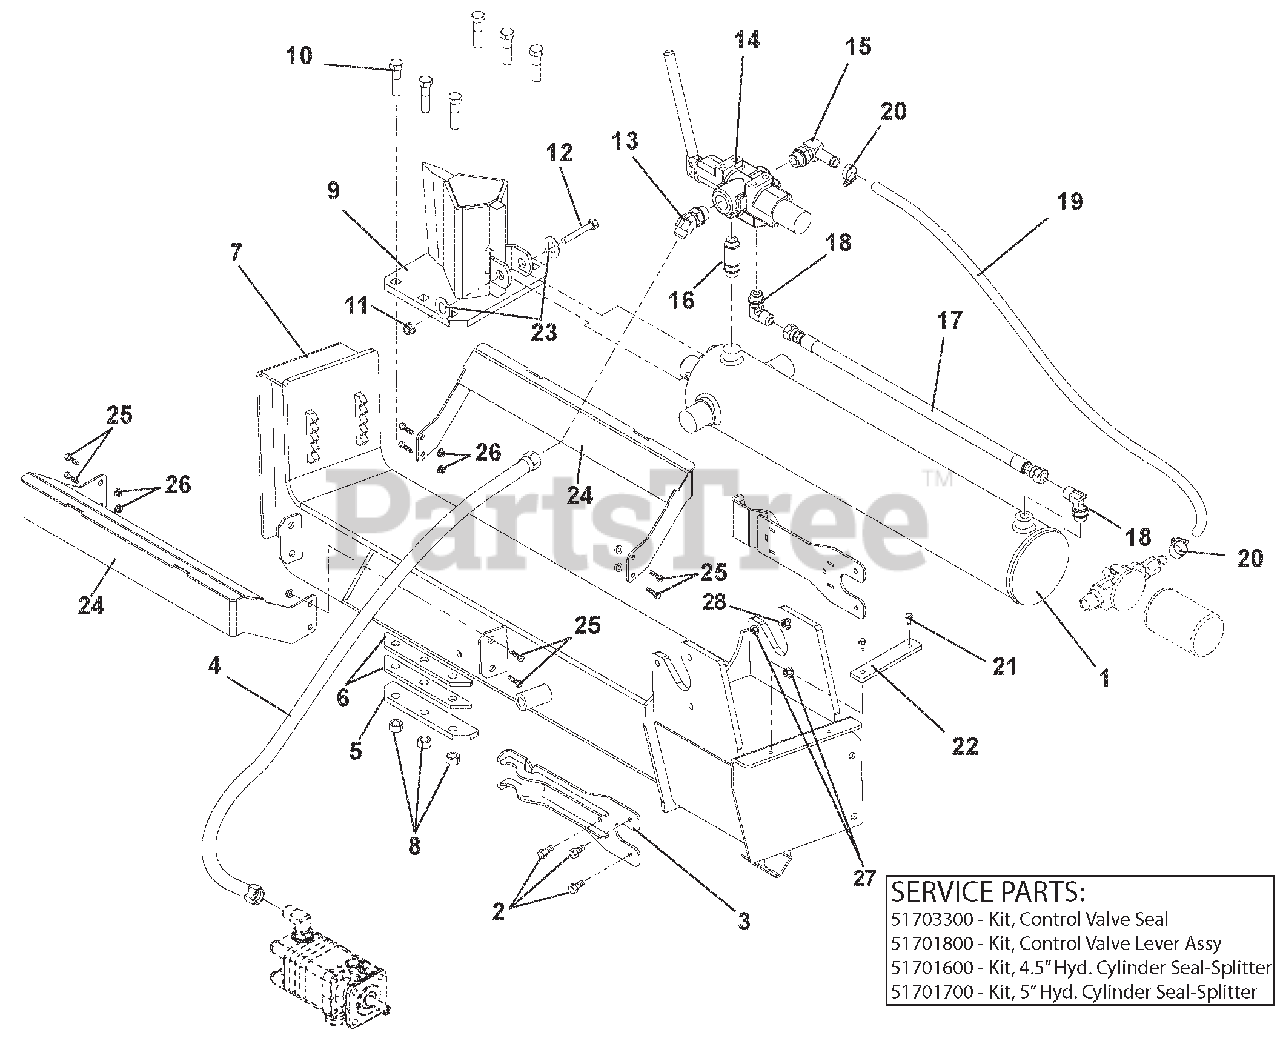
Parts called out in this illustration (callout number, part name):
1	CYLINDER,4.5 W/DECALS
1	KIT,4.5" HYD CYL SEAL-SPLITTER
1	CYLINDER, 5' W/DECALS
1	KIT, 5" HYD CYL SEAL-SPLITTER
2	@BLT-HEX .31-18X1.00 GR5 YWZC
3	WLDMT, PLATE - STRIPPER
4	HOSE, ASM - 46"
5	RETAINER,WEDGE
6	SPACER, WEDGE
7	WLDMT, BEAM - 27/34T SPLITTER
8	NUT-LK-CTR-FLG .50-13 YWZC
9	WMT, WEDGE - SPLITTER
10	BLT-RDHDSQNKFTH.50-13X2 G8YWZC
11	@NUT-LK-NYL-FLG .50-13 YWZC
12	@BLT-HEX .50-13X3.25 GR5 YWZC
13	FTG,HYD 6802-8-10
14	VALVE CONTROL-SPLITTER
14	KIT,CONTROL VALVE SEAL
14	KIT,CONTROL VALVE LEVER ASSY
15	FTG,HYD 4601-10-10
16	FTG,HYD 6403-NWO-8-8-L
17	HOSE, HYD - 22"
18	FTG,HYD 6801-8-8
19	HOSE,HYD RETURN 10LOLA X 53"
20	CLAMP,.88 DIA. HOSE
21	SCR-TAP .25-20X.50 HWH TR YWZ
22	SPACER, CYLINDER
23	@WSHR-FL-STL.563X1.38X.109YWZC
24	WLDMT, CRADLE, LOG SPLITTER
25	@BLT-HEX .38-16X1.00 GR5 YWZC
26	@NUT-LK-TOP-FLG .38-16 YWZC
27	NUT-WELD .31-18
28	@NUT-LK-TOP-FLG .31-18 YWZC
